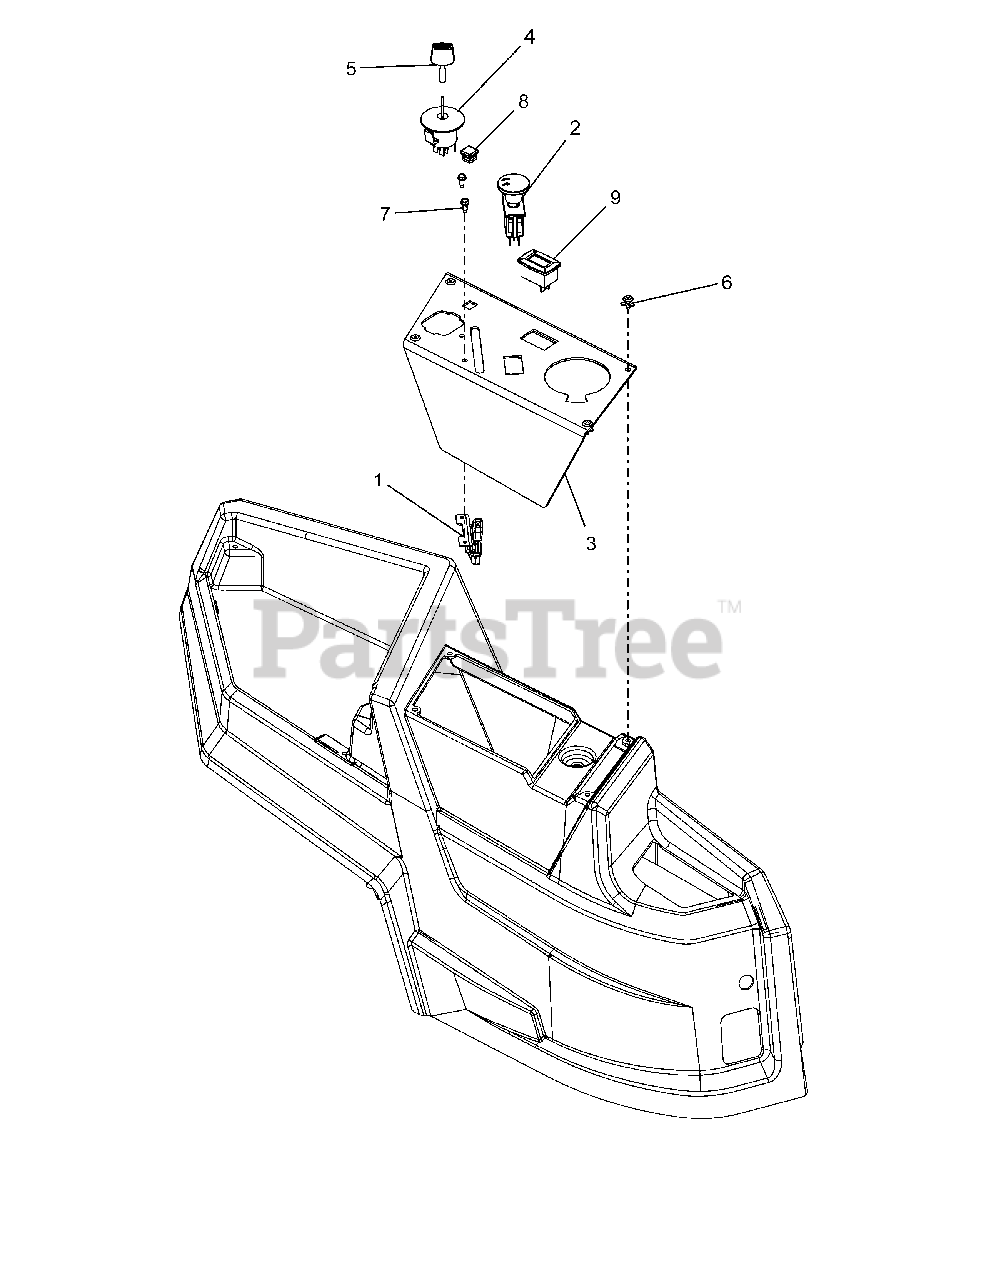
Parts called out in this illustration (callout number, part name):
1	CABLE - THROTTLE CONTROL
2	SWITCH, CLUTCH (YELLOW)
3	PANEL, CONTROL
4	KEYSWITCH-IGNITION 4 POS
5	KEY, IGNITION
6	RIVET, PLASTIC .195 DIA.
7	SCR,TAP #10-24X.50 HWH TR ZCC
8	PLUG, 5/8" SQ BLACK (14-20GA)
9	METER, HOUR W/MAINTENANCE
